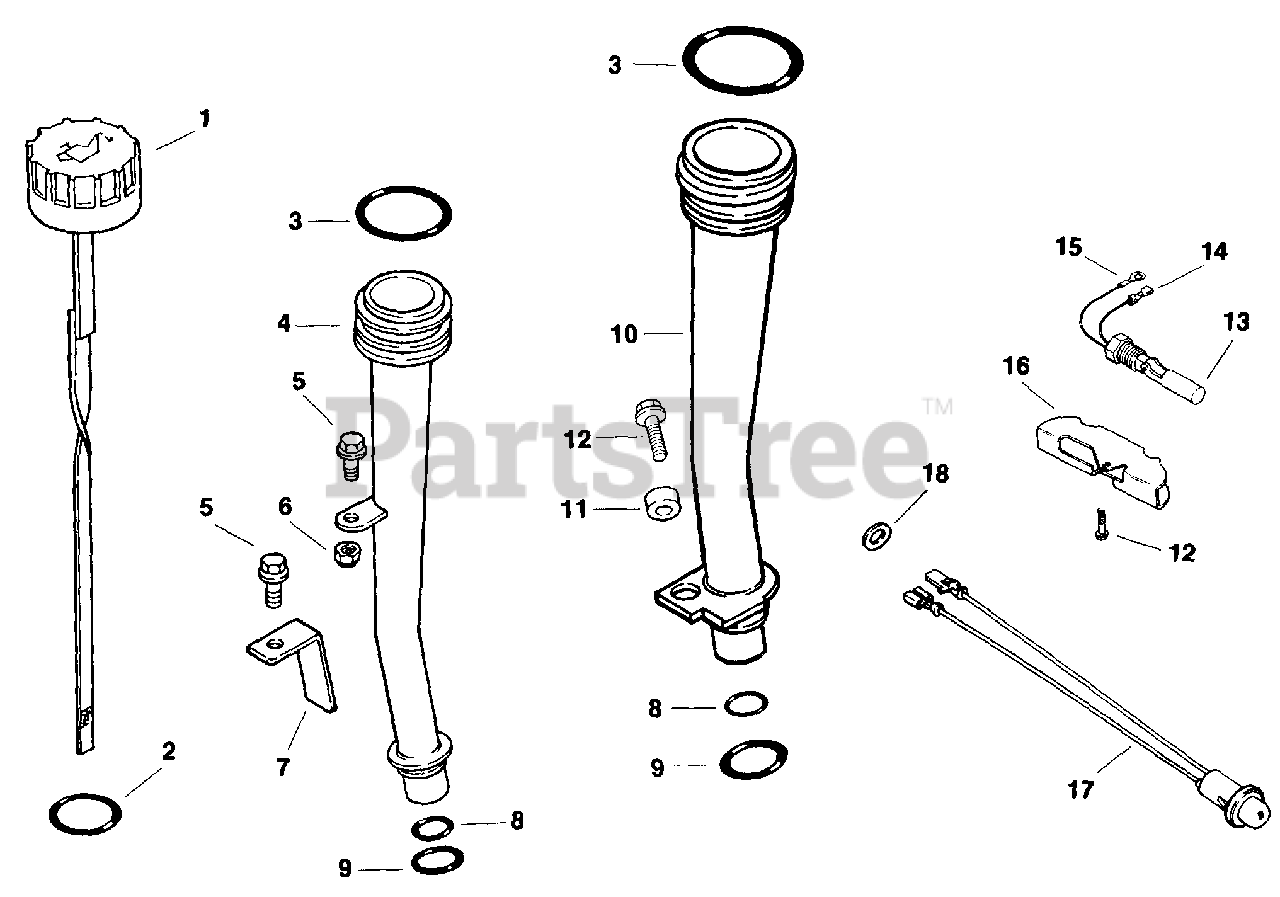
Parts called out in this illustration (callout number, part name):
1	DIPSTICK
2	O-RING - USE 25 153 02-S
3	O-RING, UPPER OIL FILL TUBE
9	O-RING, LOWER OIL FILL TUBE
10	TUBE - DISCONTINUED
12	SCREW - USE M-545016
13	SWITCH, OIL LEVEL - DISC.
15	TERMINAL - DISCONTINUED
16	BAFFLE, OIL SENTRY - DISC.
